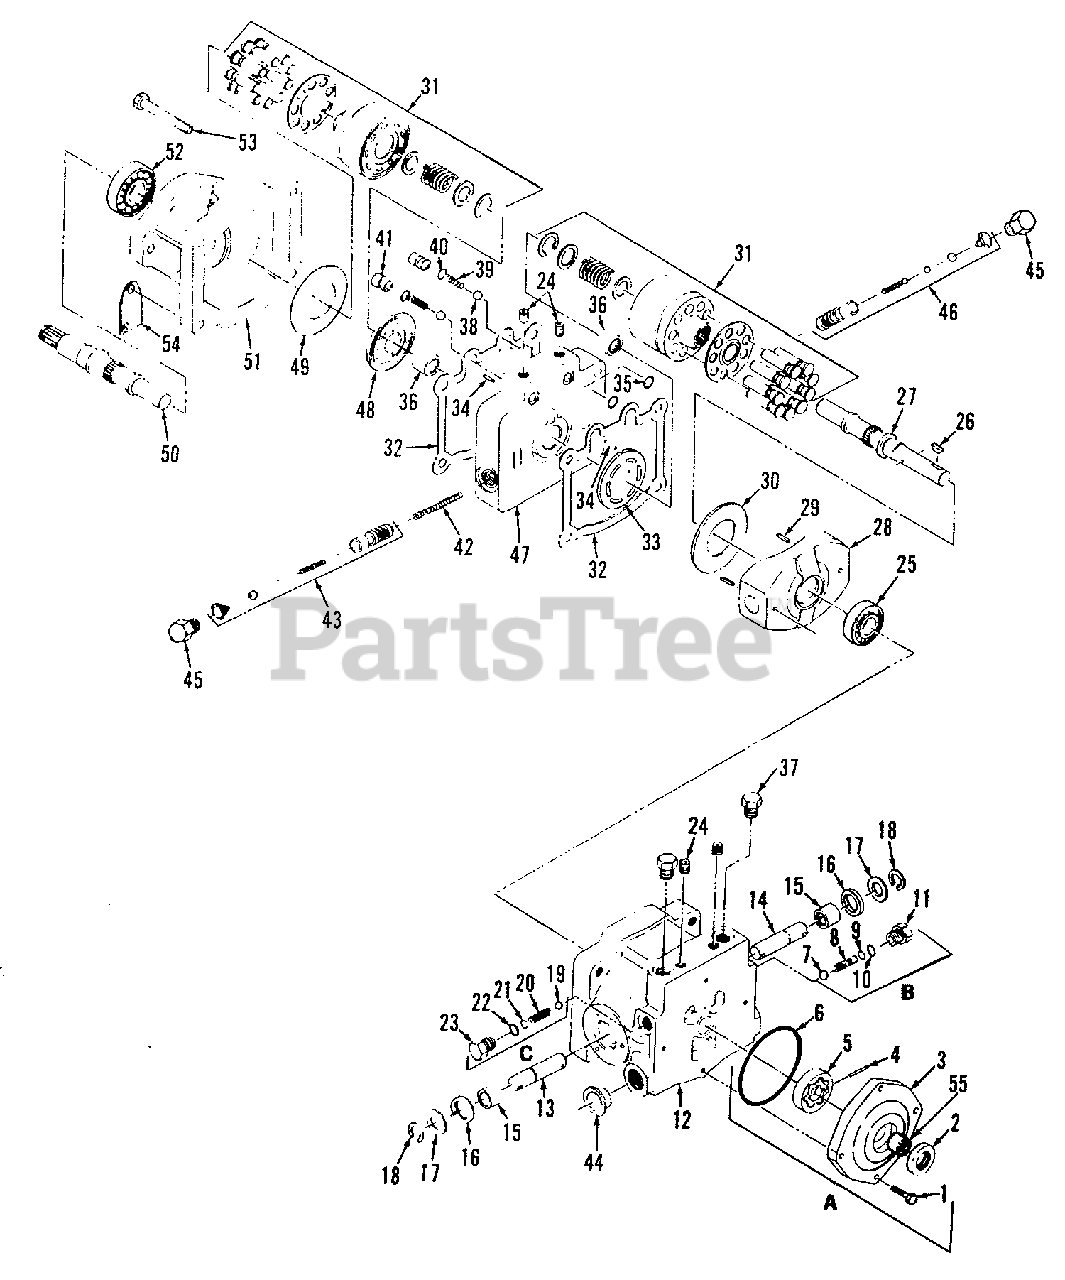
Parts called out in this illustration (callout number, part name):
1	CAPSCREW, Hex Head
3	CHARGE PUMP HOUSING
4	PIN, Headless
5	GEROTOR ASSEMBLY
7	IMPELLER RELIEF VALVE
8	IMPELLER RELIEF VALVE SPRING
11	PLUG, Hex Head
12	PUMP HOUSING
13	SHAFT, Trunnion
14	SHAFT, Trunnion
15	NEEDLE BEARING
18	RING, Retaining
20	CHANGE RELEIF VALVE SPRING
23	PLUG, Hex Head
25	BALL BEARING
26	WOODRUFF KEY
27	PUMP SHAFT
28	SWASH PLATE
29	COILED SPRING PIN
30	PLATE, Thrust
31	CYLINDER BLOCK KIT
33	PLATE, Valve
34	PIN, Headless
36	BEARING, Needle
37	PLUG, Plastic
39	CHECK VALVE SPRING
40	RING, "O"
41	CHECK VALVE SPRING
42	ACCELERATION SPRING
43	ACCELERATION VALVE
44	PLUG, Plastic
45	PLUG, Hex Head
46	ACCELERATION VALVVE
47	CENTER SECTION
48	PLATE, Valve
49	PLATE, Thrust
50	SHAFT, Motor
51	HOUSING, Motor
52	BEARING, Ball
53	CAPSCREW, Hex Head
54	PLATE, Name
55	BEARING, Needle
